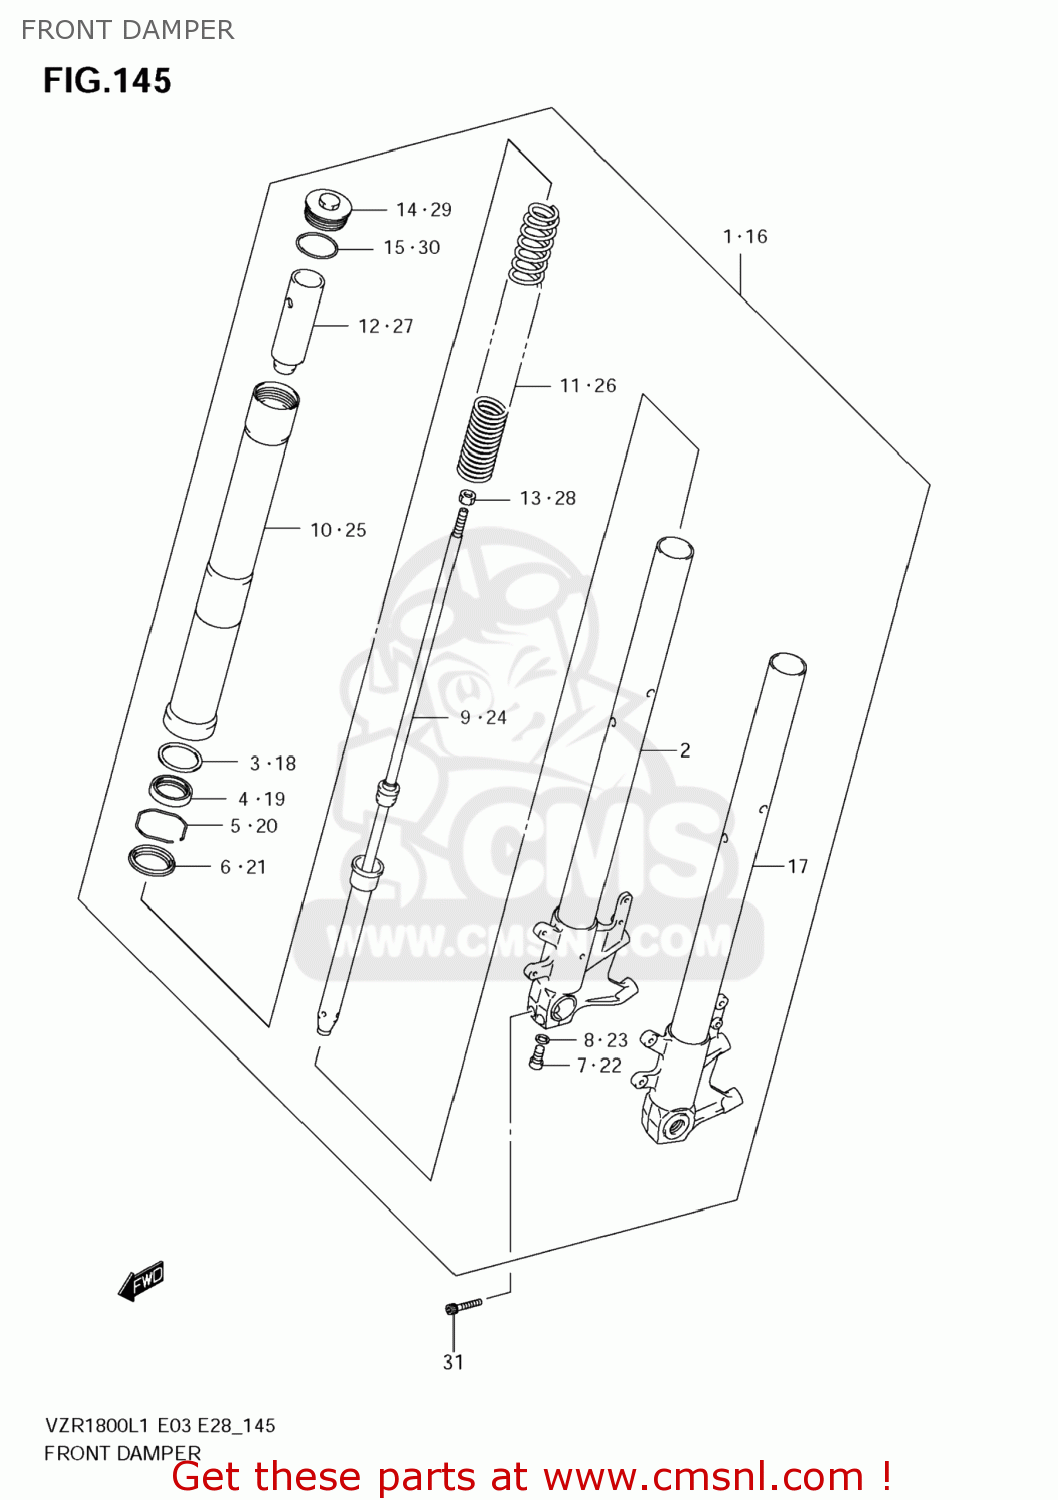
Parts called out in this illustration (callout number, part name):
1	DAMPER ASSY,FR FORK,R
2	TUBE,INNER,R
3	WASHER
4	SEAL,OIL
5	RING,STOPPER
6	SEAL,DUST
7	BOLT
8	GASKET (NAS)
9	CYLINDER
10	TUBE,OUTER
11	SPRING,FR
12	SPACER,SPRING
13	NUT,ROD
14	CAP
15	O RING
16	DAMPER ASSY,FR FORK,L
17	TUBE,INNER,L
18	WASHER
19	SEAL,OIL
20	RING,STOPPER
21	SEAL,DUST
22	BOLT
23	GASKET (NAS)
24	CYLINDER
25	TUBE,OUTER
26	SPRING,FR
27	SPACER,SPRING
28	NUT,ROD
29	CAP
30	O RING
31	BOLT,HOLDER HANDLE UPR
